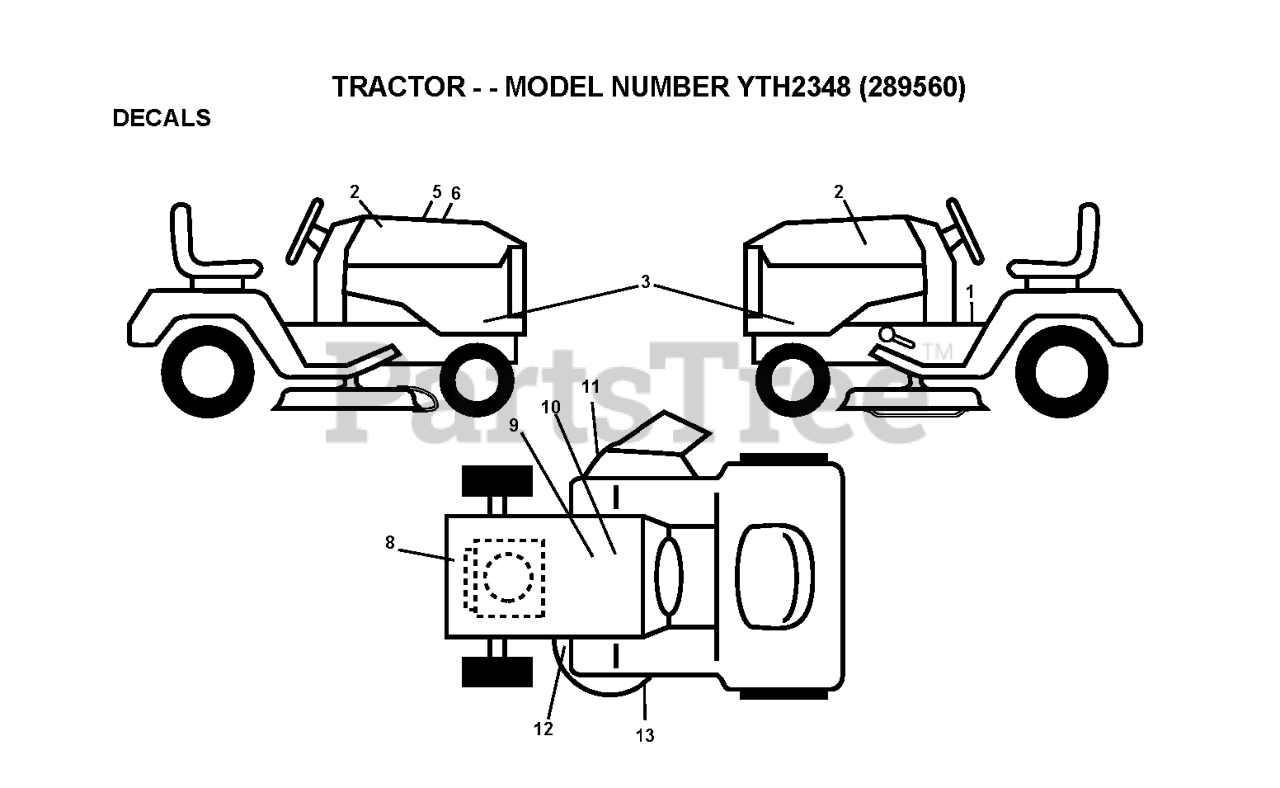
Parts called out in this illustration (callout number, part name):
1	DECAL.FENDER.WARNING.ENG
2	DECAL.HOOD.LOGO.ORANGE.HUSQVAR
3	DECAL, PANEL SIDE
5	DECAL.WARNING.CUST.RESP.E85.
8	DECAL, ENG. HP
9	DECAL BTRY SYMBOLS
10	DECAL.BATTERY
11	DECAL.WARN.KEEP.HAND.AWAY
12	DECAL CLUTCH/BRAKE
13	DECAL.MOWER.SCH.48/54
